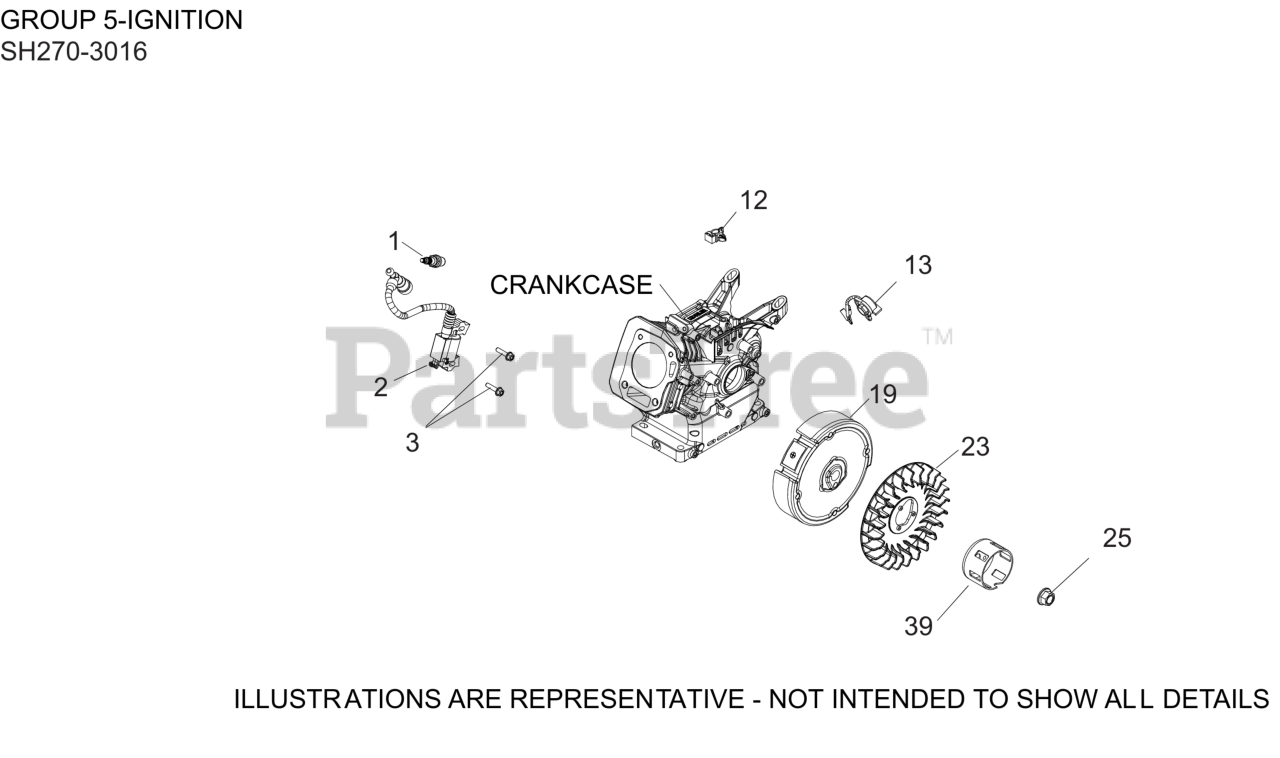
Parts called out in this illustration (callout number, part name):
1	SPARK PLUG
2	MODULE, IGNITION
3	SCREW, M6 X 25-(#25086436S)
12	CLIP, WIRE HARNESS
13	SWITCH, IGNITION
19	FLYWHEEL, ASSEMBLY
23	FAN, FLYWHEEL
25	NUT, FLYWHEEL (W/SERRATIONS)
39	STARTER CUP
